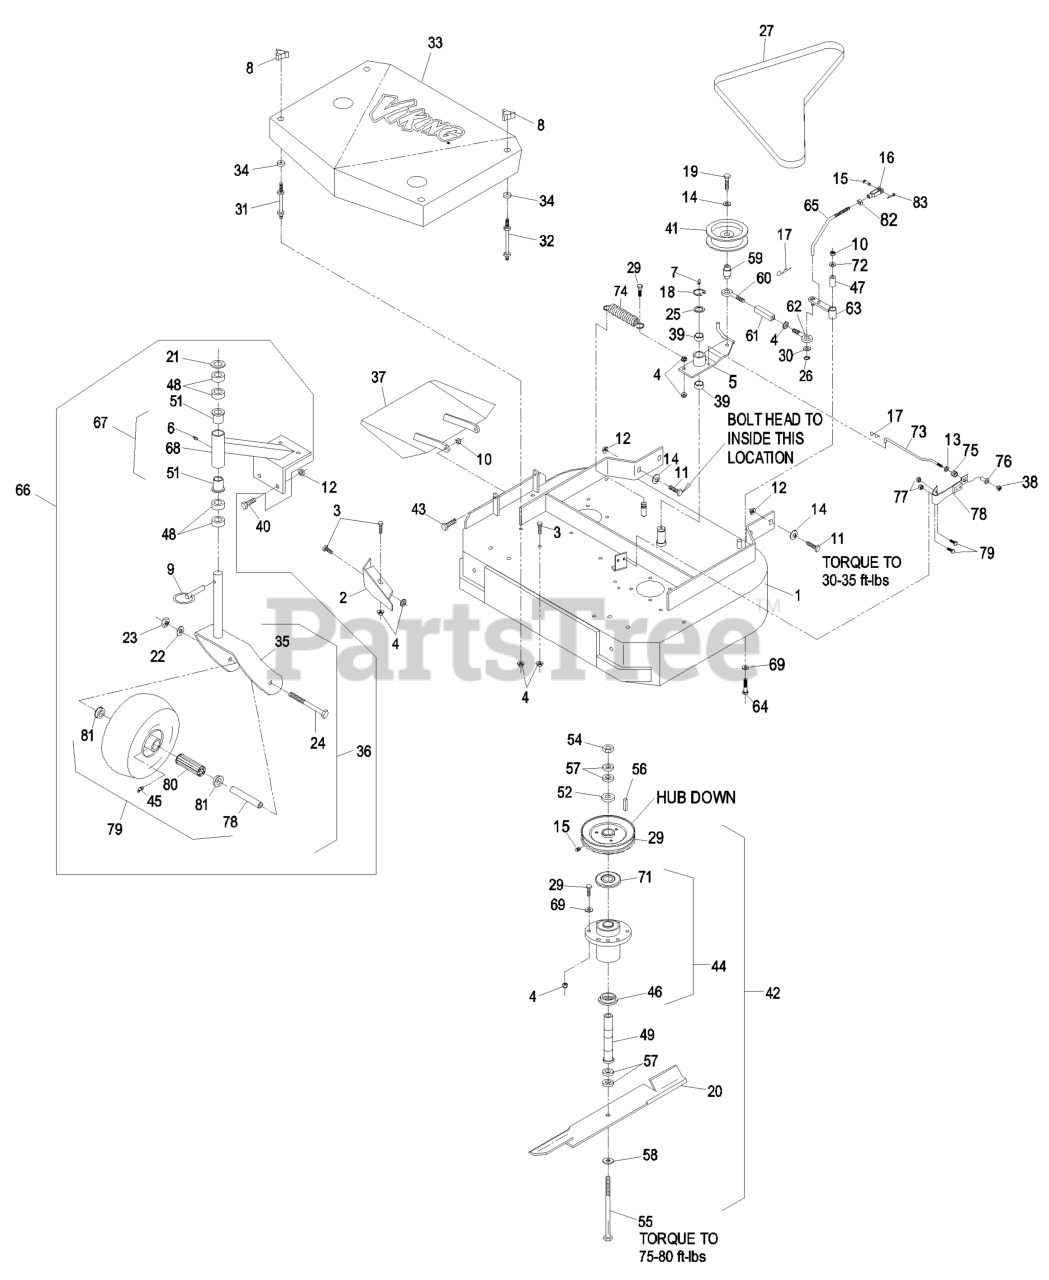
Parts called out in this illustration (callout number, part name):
1	ASM,DECK 36 RIGID
2	BAFFLE-DOGLEG
3	SCREW-HH
5	IDLER ARM ASM
6	FITTING-GREASE
7	FITTING-GREASE
8	KNOB-3 PRONG
10	NUT-LOCK, NI
11	SCREW-HH
12	NUT-HHF, WHIZ
13	RING-PUSH ON
14	WASHER-BELLEVILLE
15	PIN-CLEVIS
16	YOKE-ADJUSTABLE
17	PIN-COTTER
18	RING-RETAINING, EXT
19	SCREW-HH
21	WASHER-FLAT
22	WASHER-LOCK
23	NUT-HH
24	SCREW-HH
25	WASHER-SPINDLE
26	RING-RETAINING, EXT
27	BELT,BLADE VIKING HYD 36
28	SCREW-SET
29	SCREW-HH
30	WASHER-PLAIN
31	STUD-SHIELD, BELT (SHORT)
32	STUD-SHIELD, BELT (LONG)
33	STUD-SHIELD, BELT (LONG)
36	ASM,CASTER/WHEEL
37	WLD,CHUTE 36 RIGID
38	NUT-LOCK, NI
39	SLEEVE-BEARING
40	SCREW-HH
43	SCREW-HH
45	FITTING-GREASE
46	SPACER-GUARD, BOTTOM
47	TUBE-PIVOT
48	SPACER-CASTER
49	TUBE-SPINDLE, SHORT
50	SCREW-HH
51	BEARING-FLANGED
52	WASHER-RETAINER, SHEAVE
53	SHEAVE
54	NUT-HEX
55	SCREW-CAP, HH
58	WASHER-SPRING
59	BUSHING-ENGAGEMENT
60	EYEBOLT-THREAD, LH
61	BODY-TURNBUCKLE
62	EYEBOLT-THREAD, RH
63	ARM-ASSIST, 32/36
64	SCREW-HH
65	ARM-LINKAGE, ASSIST
67	ASM,CSTR SUPPORT W/WEIGHT
69	WASHER-SPRING
70	PAD AND SPRING ASM
71	GUARD-BEARING, TOP
72	WASHER-FLAT
73	ROD-BRAKE
74	SPRING-EXTENSION
75	SPRING-COMPRESSION
76	SPACER-FLANGED
77	NUT-LOCK, NI
78	SPACER FRONT CASTER
79	KIT, SP CASTER WHEEL REPL
80	BEARING
81	BUSHING, SP CASTER
82	NUT-HEX
83	PIN-COTTER
